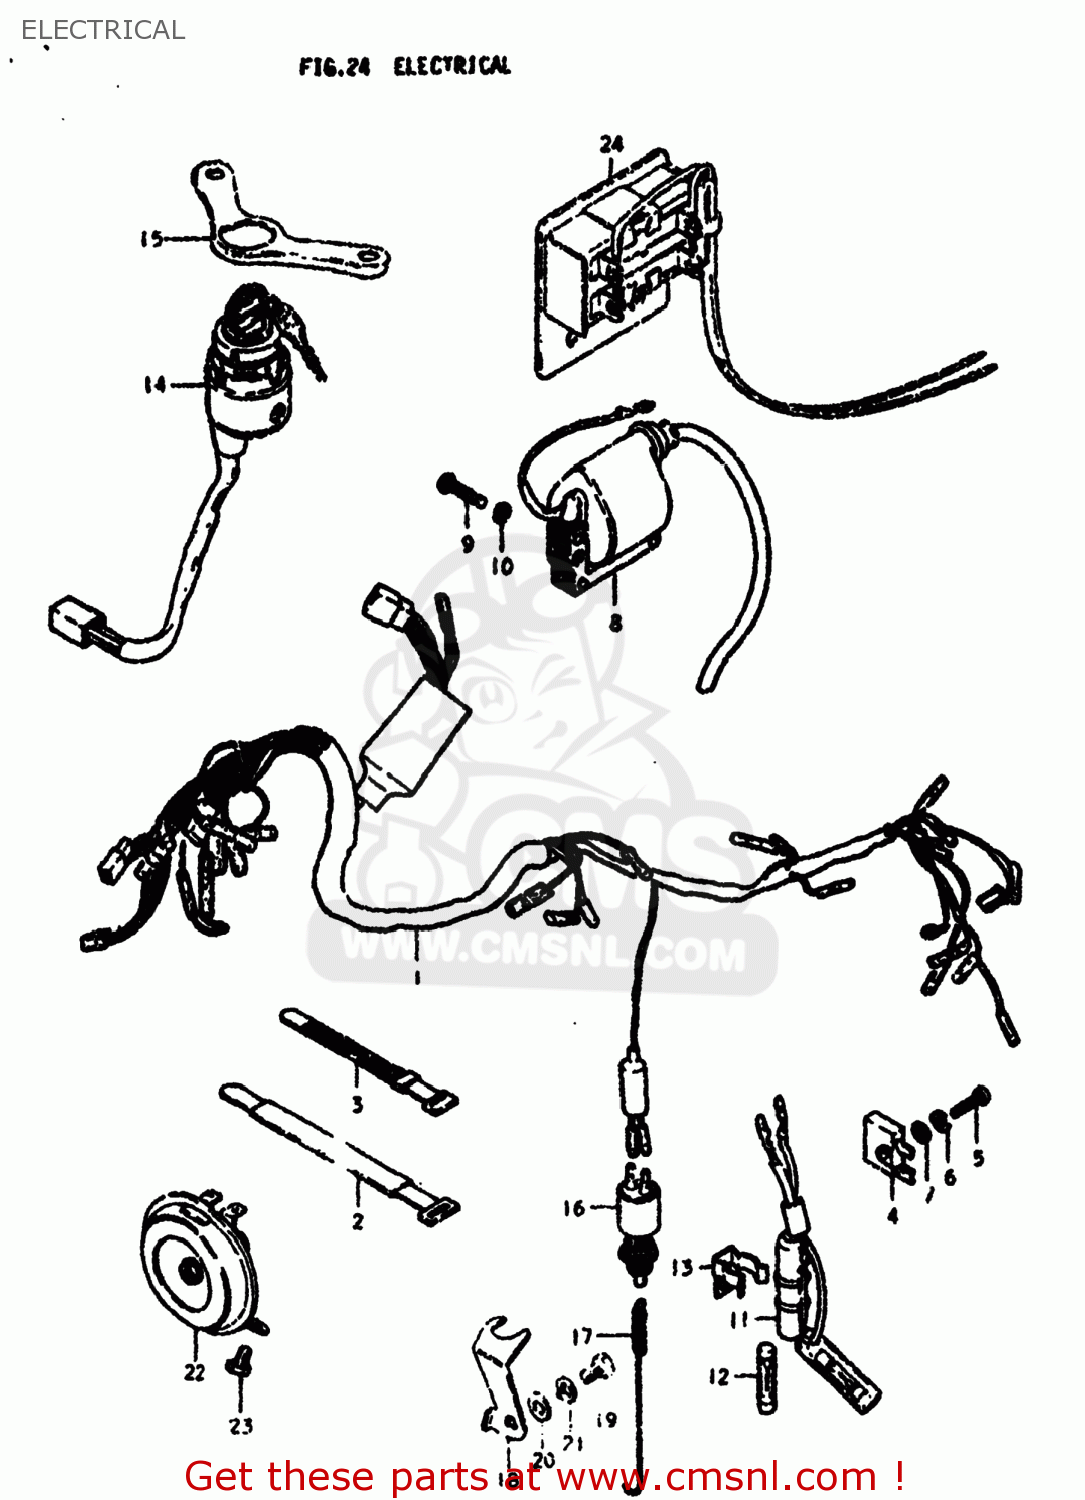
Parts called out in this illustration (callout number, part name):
1	HARNESS,WIRING
2	CLAMP
3	CLAMP(L:120)
4	RECTIFIER ASSEMBLY
5	SCREW 5X20
6	LOCK WASHER
7	WASHER
8	COIL ASSEMBLY,IGNITION
9	SCREW
10	LOCK WASHER
11	BOX ASSEMBLY,FUSE
12	FUSE(15A)
13	HOLDER,FUSE CASE
14	SWITCH ASSEMBLY,IGNITION
15	BRACKET,IGNITION SWITCH
16	SWITCH ASSY,BRAKE LAMP
17	SPRING
18	BRACKET,STOP LAMP SWITCH
19	BOLT
20	WASHER
21	LOCK WASHER
22	HORN ASSEMBLY
23	BOLT
24	REGISTER ASSEMBLY
